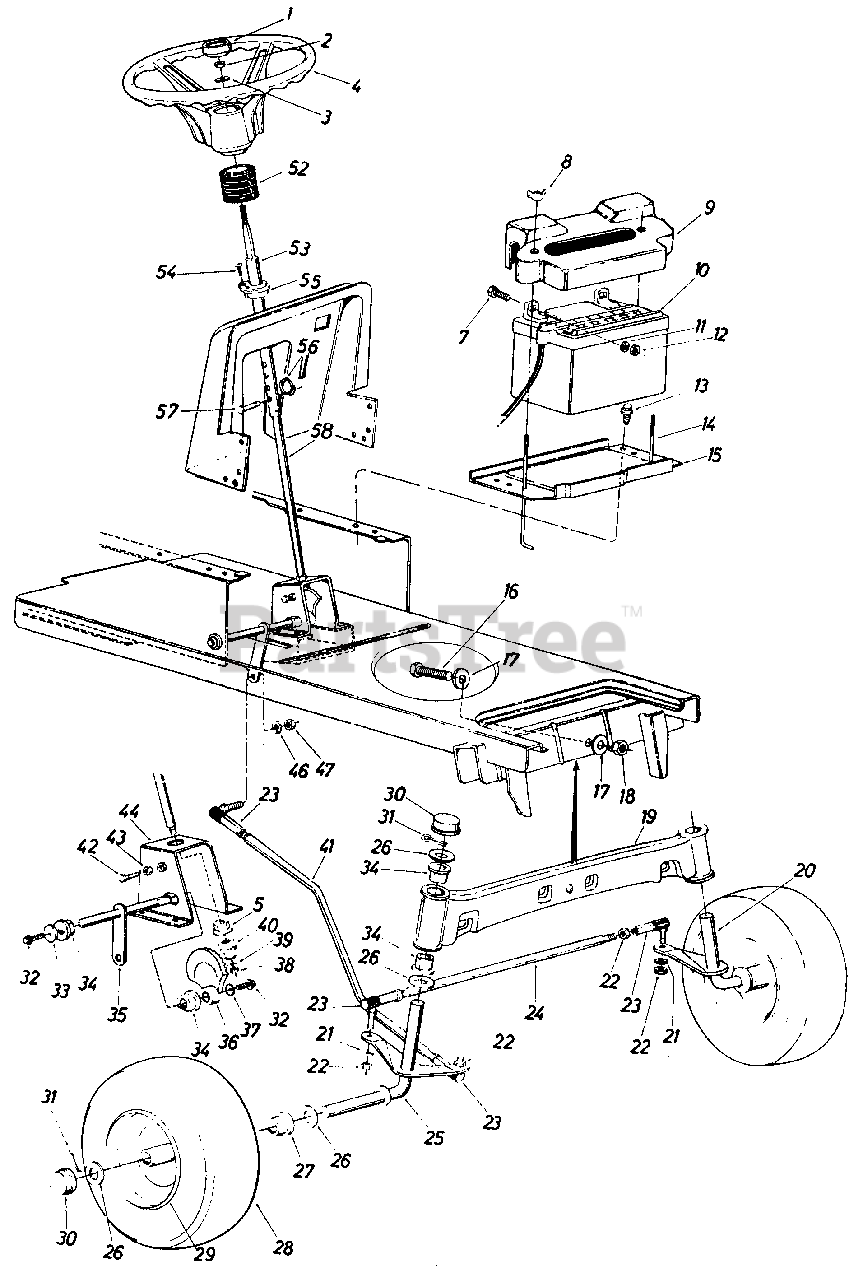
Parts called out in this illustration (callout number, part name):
1	Steering Wheel Cap
2	Hex Cent. L-Nut 5/16-18 Thd
3	Bell-Wash. 5/16" I.D. x .87" O.D. x .060
4	Steering Wheel
5	Plastic Hex Bearing 5/8" I.D.
7	Hex Scr. 1/4-20 x .62" Lg.
8	Wing Nut Plastic 1/4-20 Thd.
9	Battery Cover
10	12-V Battery
11	L-Wash 1/4" I.D.
12	Hex Nut 1/4-20 Thd.
13	Hex Thd. Rolling Scr. 1/4-20 x.50" Lg.
14	Battery Hold Down Rod
15	Battery Plate
16	Hex Scr. 5/8-18 x 2.50" Lg.
17	Flat Wash. .66" I.D. x 2.25" O.D. x .17
18	Hex Cent. L-Nut 5/8-18 Thd.
19	Front Pivot Bar Ass'y.
20	Front Axle Ass'y. L.H.
21	L-Wash. 3/8" I.D.
22	Hex Nut 3/8-24 Thd.
23	Ball Joint Ass'y.
24	Tie Rod
25	Front Axle Ass'y. R.H.
26	Fl-Wash. .780 I.D. x 1.59 O.D.
27	Flange Bearing
28	Front Wheel Ass'y. Comp.
29	Front Wheel Rim Only
30	Dust Cover
31	Cotter Pin 5/32" Dia. x 1.00" Lg.
32	Hex Scr. 3/8-24 x .75" Lg. Grade 5
33	Fl-Wash. 3/8 I.D. x 1.25 O.D. x .090
34	Flange Double "D" Brg. .753 I.D.
35	Steering Arm Shaft Ass'y.
36	Side Gear Steering
37	Bell-Wash. 3/8" I.D.
38	Hex Cent. L-Nut 5/16-24 Thd.
39	Fl-Wash. 5/16" I.D. x .62 O.D. x .059
40	Pinion Gear Steering
41	Drag Link
42	Hex Nylon Scr. 3/8-16 x 1.25" Lg.
43	Hex Nut 3/8-16 Thd.
44	Steering Gear Sup. Ass'y.
46	L-Wash. 3/8" I.D.
47	Hex Nut 3/8-24 Thd.
52	Steering Bellow
53	Upper Steering Shaft
54	Oval Hd. Cr.-Sunk Scr. #10 x 5/8" Lg.
55	Fl-Bearing .89" I.D. x 1.36" O.D.
56	Hex L-Nut 1/4-20 Thd.
57	Hex Bolt 1/4-20 x 1.31" Lg.
58	Lower Steering Shaft
